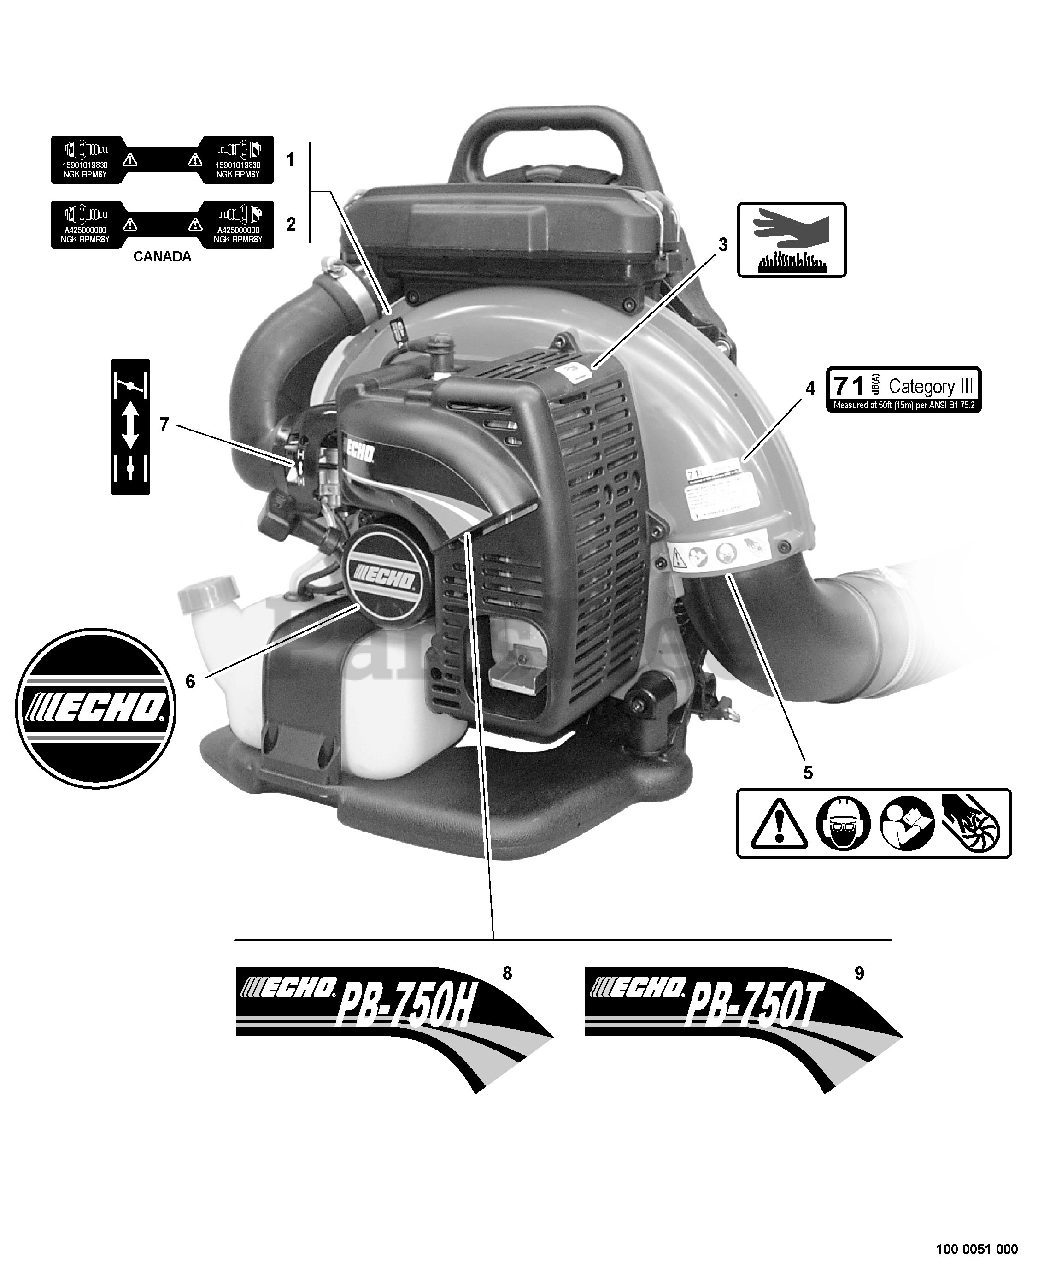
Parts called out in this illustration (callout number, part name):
1	LABEL - SPARK PLUG -- BPM-8Y
2	LABEL - SPARK PLUG -- BPMR-8Y
3	LABEL - HOT SURFACE
4	LABEL - NOISE 71dB(A) CAT III
5	LABEL - CAUTION
6	LABEL - ECHO
7	LABEL - CHOKE
8	LABEL - MODEL PB-750H
9	LABEL - MODEL PB-750T
